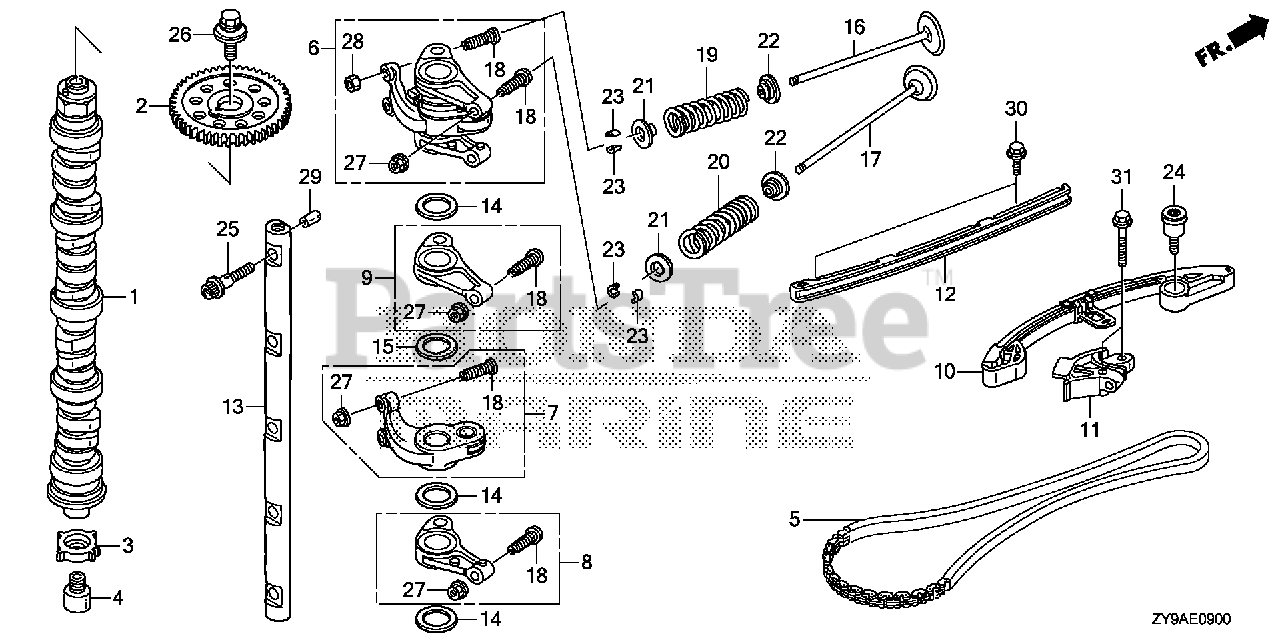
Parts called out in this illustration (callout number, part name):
2	SPROCKET, CAM CHAIN DRIVEN (46T)
3	PLATE, TDC PULSER
4	BOLT, TDC PULSER PLATE
5	CHAIN (132L)
6	ARM ASSY., ROCKER
10	TENSIONER, CAM CHAIN
11	SLIDER, CAM CHAIN TENSIONER
12	GUIDE, CAM CHAIN
13	SHAFT, ROCKER ARM
16	VALVE, IN.
17	VALVE, EX.
18	SCREW, TAPPET ADJUSTING
19	SPRING, IN. VALVE
20	SPRING, EX. VALVE
21	RETAINER, VALVE SPRING
22	SEAT, VALVE SPRING
23	COTTER, VALVE (FUJI VALVE)
24	BOLT, TENSIONER PIVOT
25	BOLT, ROCKER ARM SHAFT
26	BOLT-WASHER (10X30)
27	NUT, TAPPET ADJUSTING (TOKAI TRW)
28	NUT, TAPPET ADJUSTING
29	PIN A, DOWEL (7X12)
30	BOLT, FLANGE (6X14)
31	BOLT, FLANGE (6X28)
